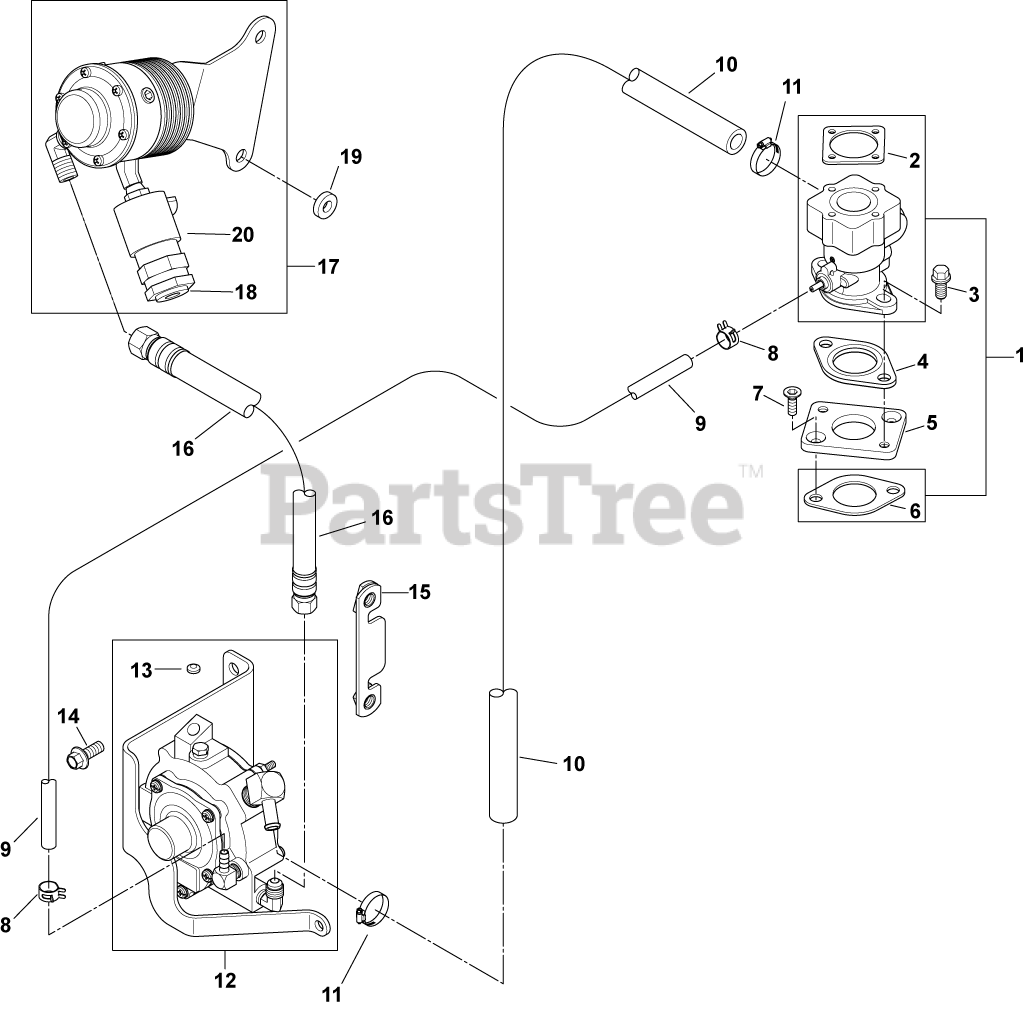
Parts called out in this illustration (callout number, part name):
1	KIT, CARBURETOR W/GASKETS - DISCONTINUED
2	GASKET, AIR CLEANER
4	GASKET, CARBURETOR
5	ADAPTER, MANIFOLD
6	GASKET, INTAKE MANIFOLD
8	CLAMP, HOSE
10	HOSE, REGULATOR
11	CLAMP, HOSE (KM)-USE 25 237 31-S
12	REGULATOR ASSEMBLY
13	PLUG, EXPANDER - DISCONTINUED
14	SCREW, FLG M8X1.25X20
15	BRACKET, MOUNTING
16	HOSE, VAPORIZER
17	VAPORIZER ASSEMBLY
18	PLUG, CAP 1/4 INCH
19	WASHER, FLAT 11/32"
20	SOLENOID, 12VDC LOCKOFF
